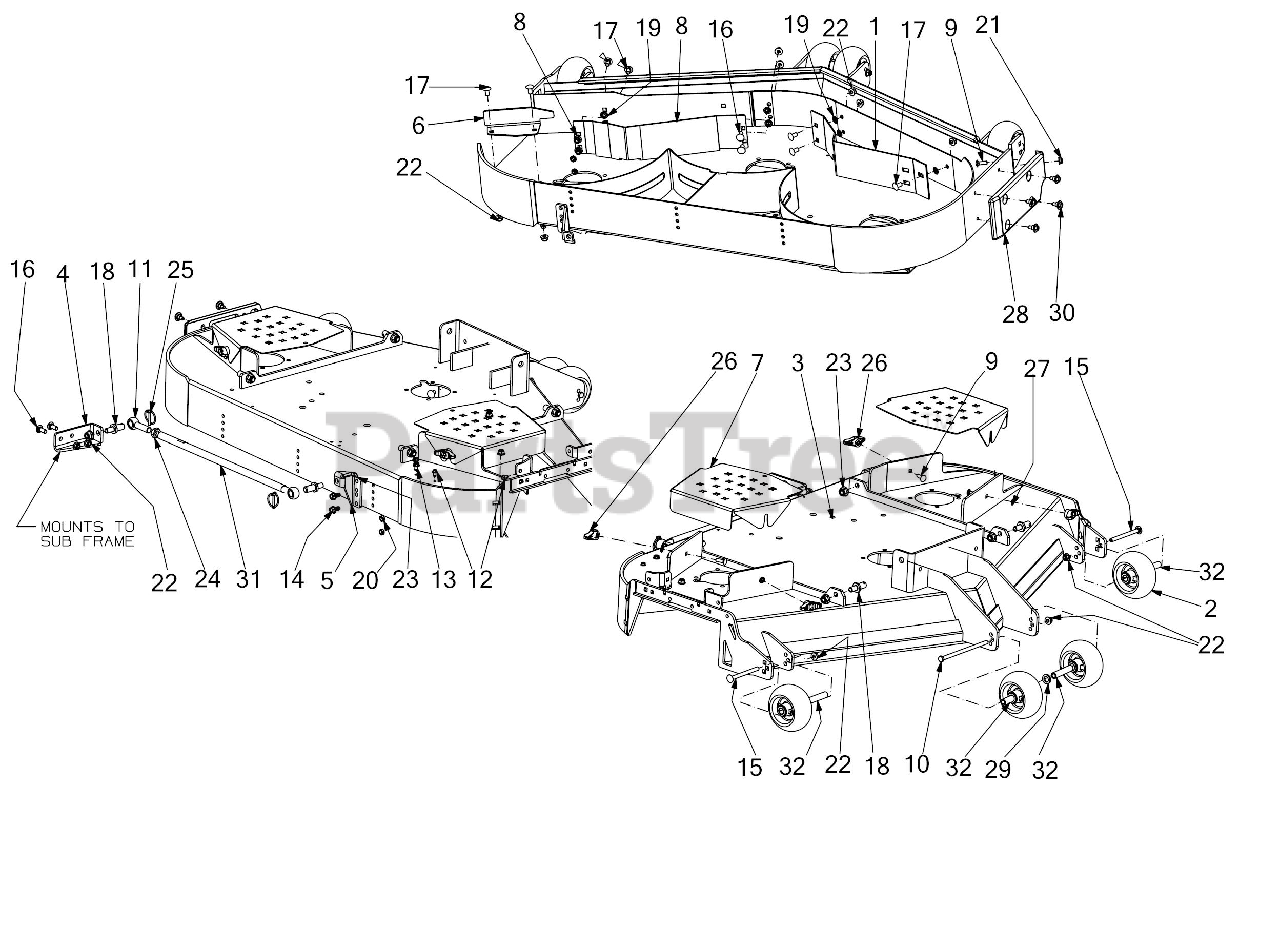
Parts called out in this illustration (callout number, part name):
1	BAFFLE - 54
2	WHEEL ASSEMBLY 5"
3	54" FAB DECK SHELL ASSEMBLY
4	STABILIZER MOUNTING BRACKET
5	REAR STABILIZER BRACKET
6	DECK CHUTE BAFFLE
7	DECK BELT COVER
9	CARRIAGE BOLT 5/16-18 x 1.00
10	SCREW 3/8-16 x 7.25 GR5
11	BOLT 5/8-16 x 2.63
12	SCREW 1/4-20 X.500
13	SCREW 5/16-18 x .500
14	SCREW 3/8-16 x 3/4
15	CARRIAGE BOLT 3/8-16 x 4.25 GR5
16	CARRIAGE BOLT 3/8-16 x 1.00 GR5
17	CARRIAGE BOLT 3/8-16 x .75
20	JAM LOCK NUT
21	FLANGE LOCK NUT 5/16-18
24	HEX NUT
26	WING KNOB 5/16-18
28	DECK SKID PLATE (LH)
29	FLAT WASHER .632X1.00X.16
30	SHOULDER SCREW .43X.29X5/16-18 TT
32	WHEEL SPACER .38ID x 3.04LG
